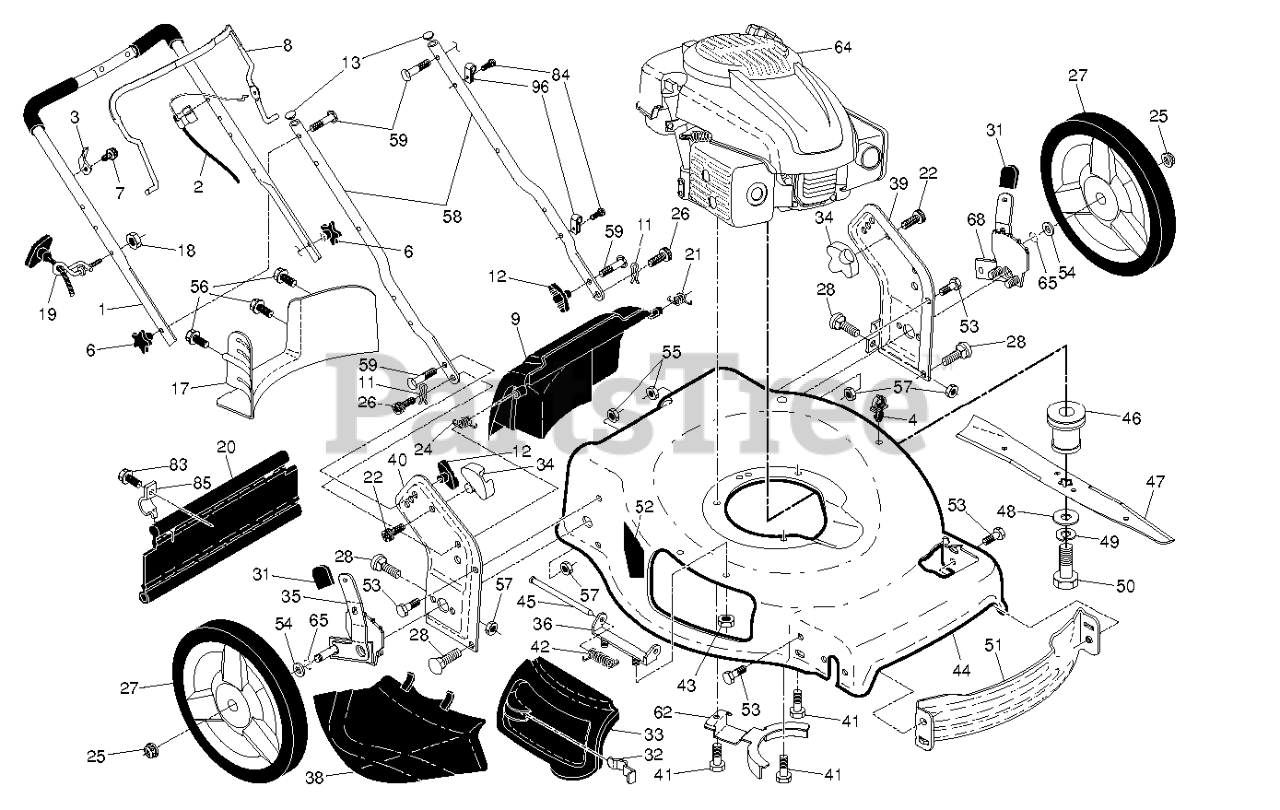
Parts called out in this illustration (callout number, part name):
1	HANDLE.ASM.GRY.W/GRIP
2	CABLE.MZR.47.75.SNAP-IN.PU.L
3	BRACKET.UPSTOP.RT
6	KNOB.HANDLE.PLASTIC.STAR.BLACK
8	BAIL.MZR.EZ2.DSTR.22+.ORG.E
9	DOOR.REAR.ASM.22+.HUSQ.FG/RGD
11	COTTER.HAIRPIN.DOOR/HANDLE.PIV
12	KNOB.WING.PLASTIC.BLACK
13	PLUG.PLASTIC.7/8".14-20.GAUGE
17	BAFFLE.22PLUS.FGD.REAR.
18	NUT
19	RB GUIDE.ROPE.STD.BLK.ZIN WSL
20	SKIRT.REAR.22PLUS.RGD/FGD.NEW
21	SPRING.LH.BLACK
22	SCREW.PAN.HEAD.#10
24	SPRING.RH.GRAY
25	NUT.HEX.FLANGE.3/8-16.LOCKNUT
26	SCREW,DOOR/HANDLE.PIVOT
27	WHEEL.12X1.75.CF.H3SPKRAD3
28	BOLT
31	SELECTOR KNOB
32	LATCH.DOOR.ZINC
33	DOOR.MULCH.22 PLUS.HUSQ.GREY
34	BRACKET.GRASSBAG.ATTACHING.BLK
35	ADJUSTER.ASM.9POS.HW.R/R
36	BRACKET.ASM.HINGE.21.FWGD.
38	DEFLECTOR.CLIPPING.22.BLACK
39	BRACKET.HANDLE.LT.22+.W/DP.GRE
40	RP.BRACKET.ASM.HANDLE.RT.22+.
41	BOLT 3/8-16X1-1/8
42	SPRING.TORSION
43	NUT.HEX.FLANGE.1/4
45	ROD.HINGE.21
46	ADPTER.BLAD.25M.VS.22PLU.STAR
47	BLADE.22PLUS
48	WASHER,HARDEN
49	LOCKWASHER
50	SCREW, HEX HD 3/8-24 X 1-3/8
51	BAFFLE.FRONT.22.PLUS
52	DANGER DECAL
53	BOLT.5/16HEX.WHS.HD
54	WASHER.FLAT.1/2
55	NUT.HEX.FLANGE.1/4
56	SCREW.HX.13X.750
57	NUT.FLANGE.5/16
58	HANDLE.LOWER.22+BT.2PC.GRY
59	BOLT, HANDLE 5/16-18X1.75
62	BRACKET.KEEPER.BELT
65	O-RING..070X.487.NEOPRENE
68	ADJUSTER.ASM.9POS.HW.R/L
83	TAPPING SCREW
84	FASTENER.PUSH.O.250X0.783
85	BRACKET.SKIRT.22+.BZP
96	CLIP.CABLE.BLK
